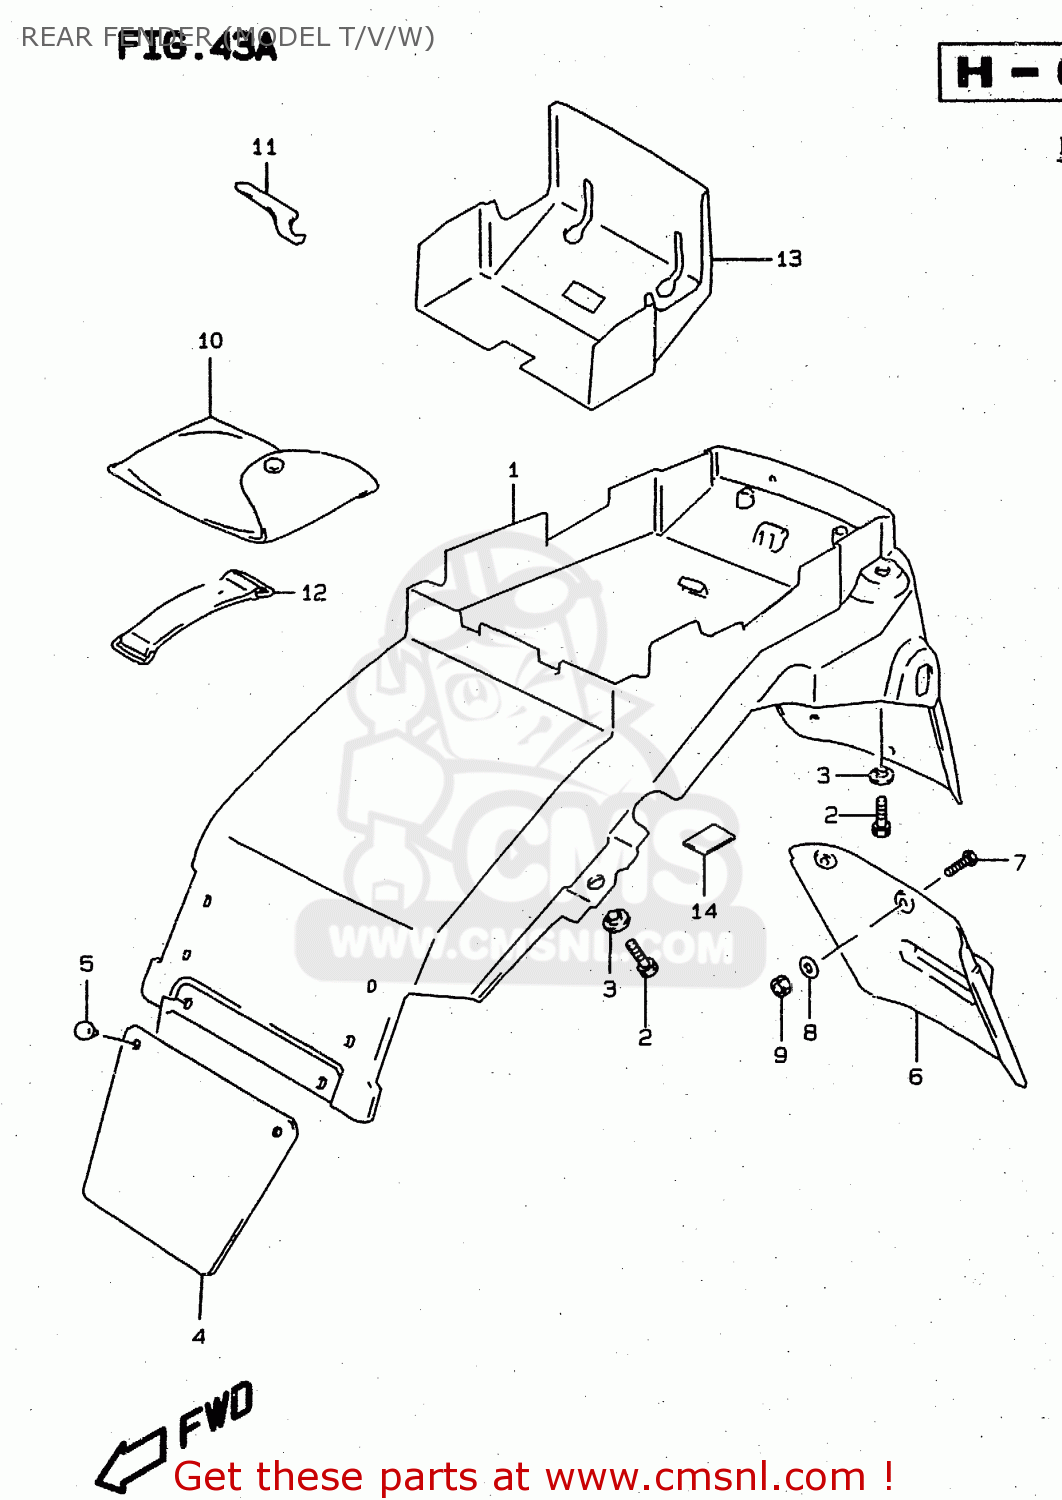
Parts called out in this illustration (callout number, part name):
1	FENDER,RR
2	BOLT
3	WASHER
4	GUARD,RR FENDER MUD
5	CLIP,MUDGUARD
6	EXTENSION,RR FENDER
7	SCREW
8	WASHER(6.5X18X1.6)
9	NUT 6MM
10	TOOL ASSY
11	CLAMP
12	BAND
13	GUARD,REAR FENDER
14	TAPE,RR FENDER
